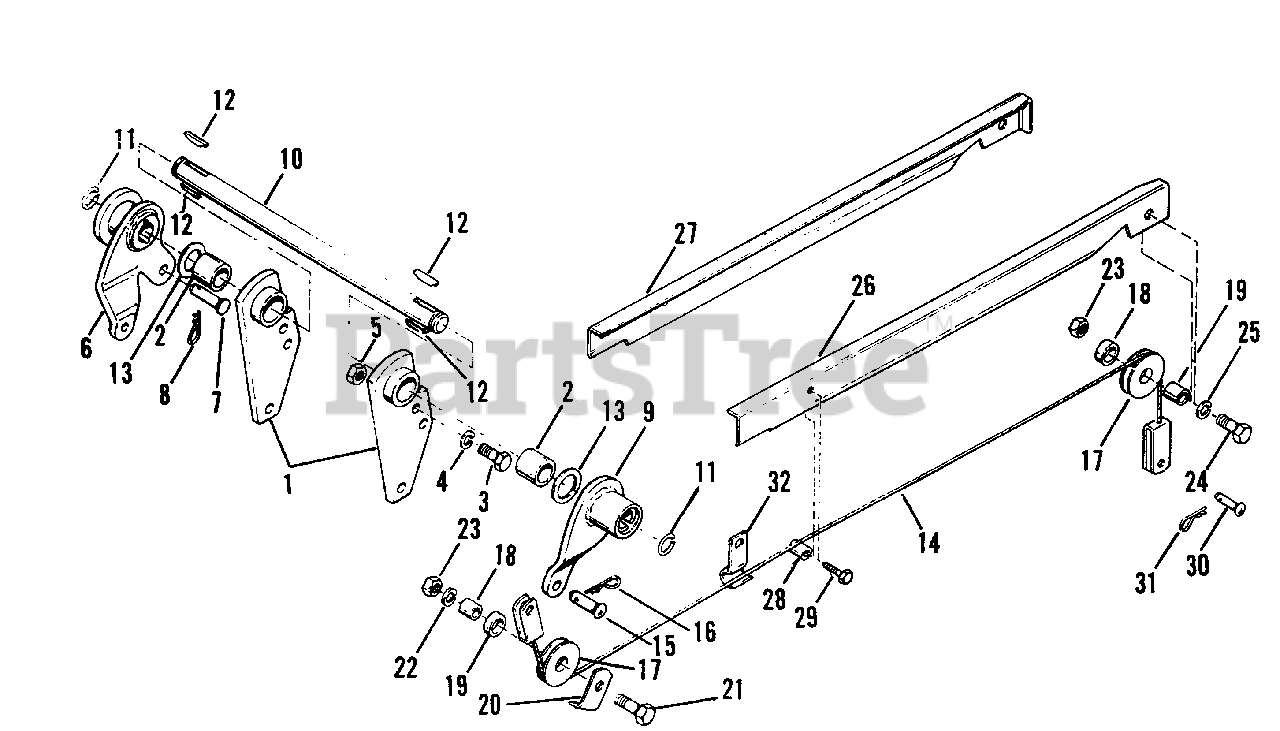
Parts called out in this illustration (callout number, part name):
1	Support Assembly
3	Hex Capscrew, 1/2"-13 x 1-1/2" lg.
4	Lock Washer, 1/2"
5	Hex Nut, Full, 1/2"-13
6	Lift Arm Assembly, L.H.
8	Hairpin Clip
9	Lift Arm Assembly, R.H.
10	Rock Shaft
11	Retaining Ring
13	Thrust Washer (As Required)
14	Cable Assembly
15	Clevis Pin
16	Hairpin Clip
20	Wire Guide
21	Hex Capscrew, 1/2"-13 x 1-3/4" lg.
22	Lock Washer, 1/2"
23	Hex Nut, 1/2"-13
24	Hex Capscrew, 1/2"-13 x 1-1/2" lg.
25	Lock Washer, 1/2"
26	Wire Guard, R.H.
27	Wire Guard, L.H.
29	Self Tapping Screw, 1/4"-20 x 1-1/4" lg.
31	Hairpin Clip
32	Wire Guide
